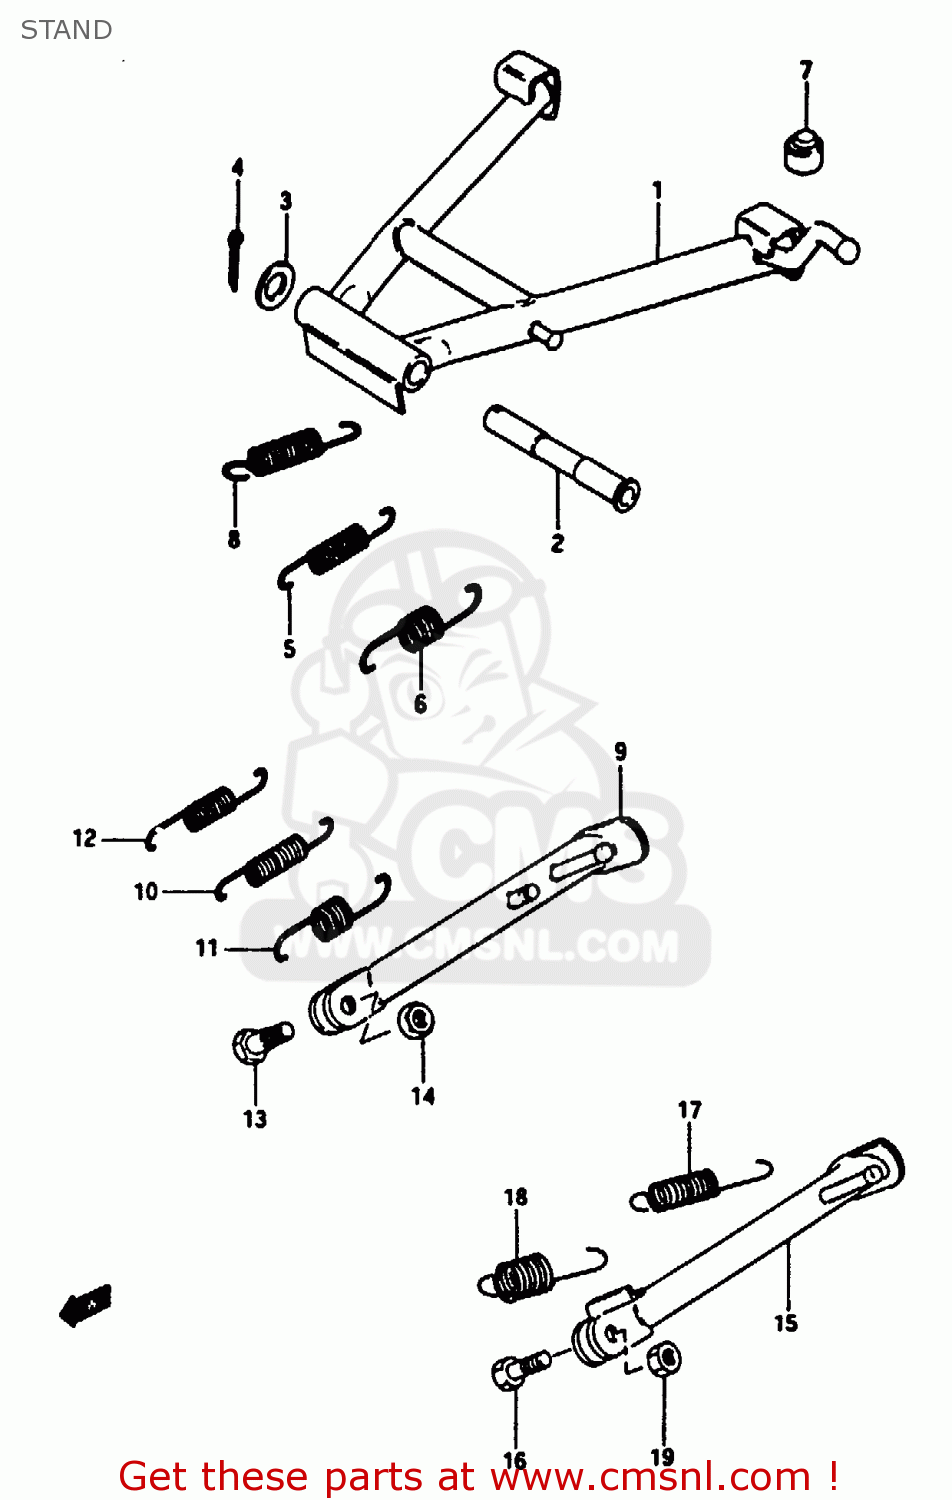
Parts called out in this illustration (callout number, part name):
1	STAND,CTR
2	SHAFT,CENTER STAND
3	WASHER(16.5X32X2.3)
4	COTTER PIN
5	SPRING
6	SPRING
7	CUSHION
8	SPRING
9	STAND,SIDE
10	SPRING
11	SPRING
12	SPRING
13	BOLT(10X30)
14	NUTM10X1.25X8
15	STAND,PROP
16	BOLT(10X30)
17	SPRING
18	SPRING
19	NUT
